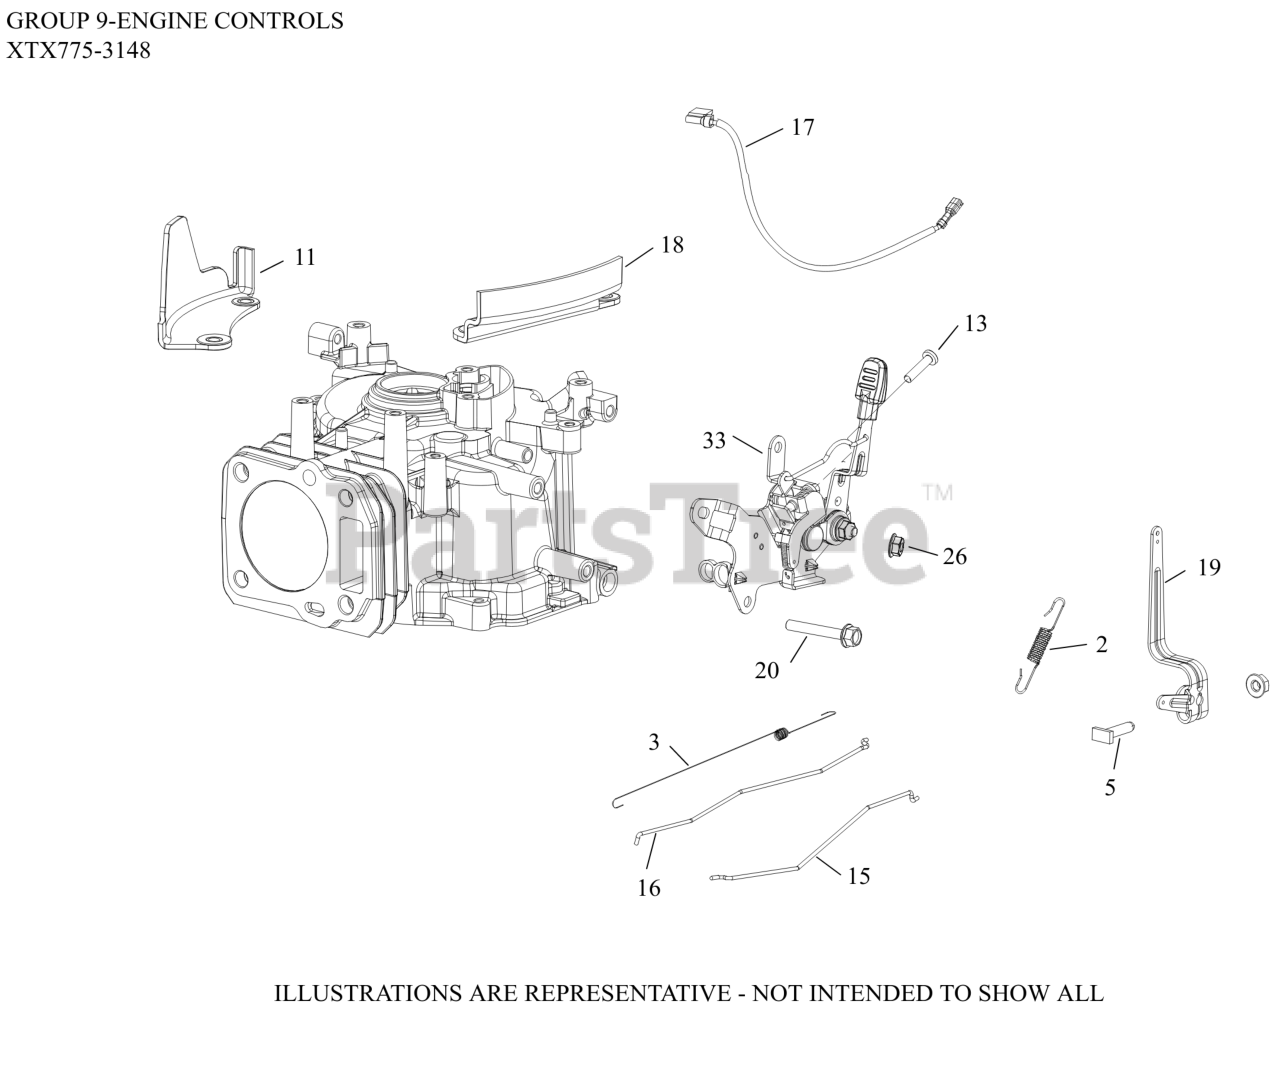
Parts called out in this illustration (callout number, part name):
2	SPRING, GOV (2800-3300 RPM)
3	SPRING, LINKAGE
5	SCREW, RECTANGLE HEAD (M6)
11	GUARD, FINGER
13	SCREW, #25 6-LOBE PAN HD (M5)
15	LINKAGE, CHOKE
16	LINKAGE, GOVERNOR
18	GUARD, FINGER
19	LEVER, GOVERNOR
20	SCREW, HEX FLANGE (M6)
26	NUT, HEX FLANGE LOCK (M6)
33	CNTRL ASSY,NON-REM VAR SPD W/CHK & KI
